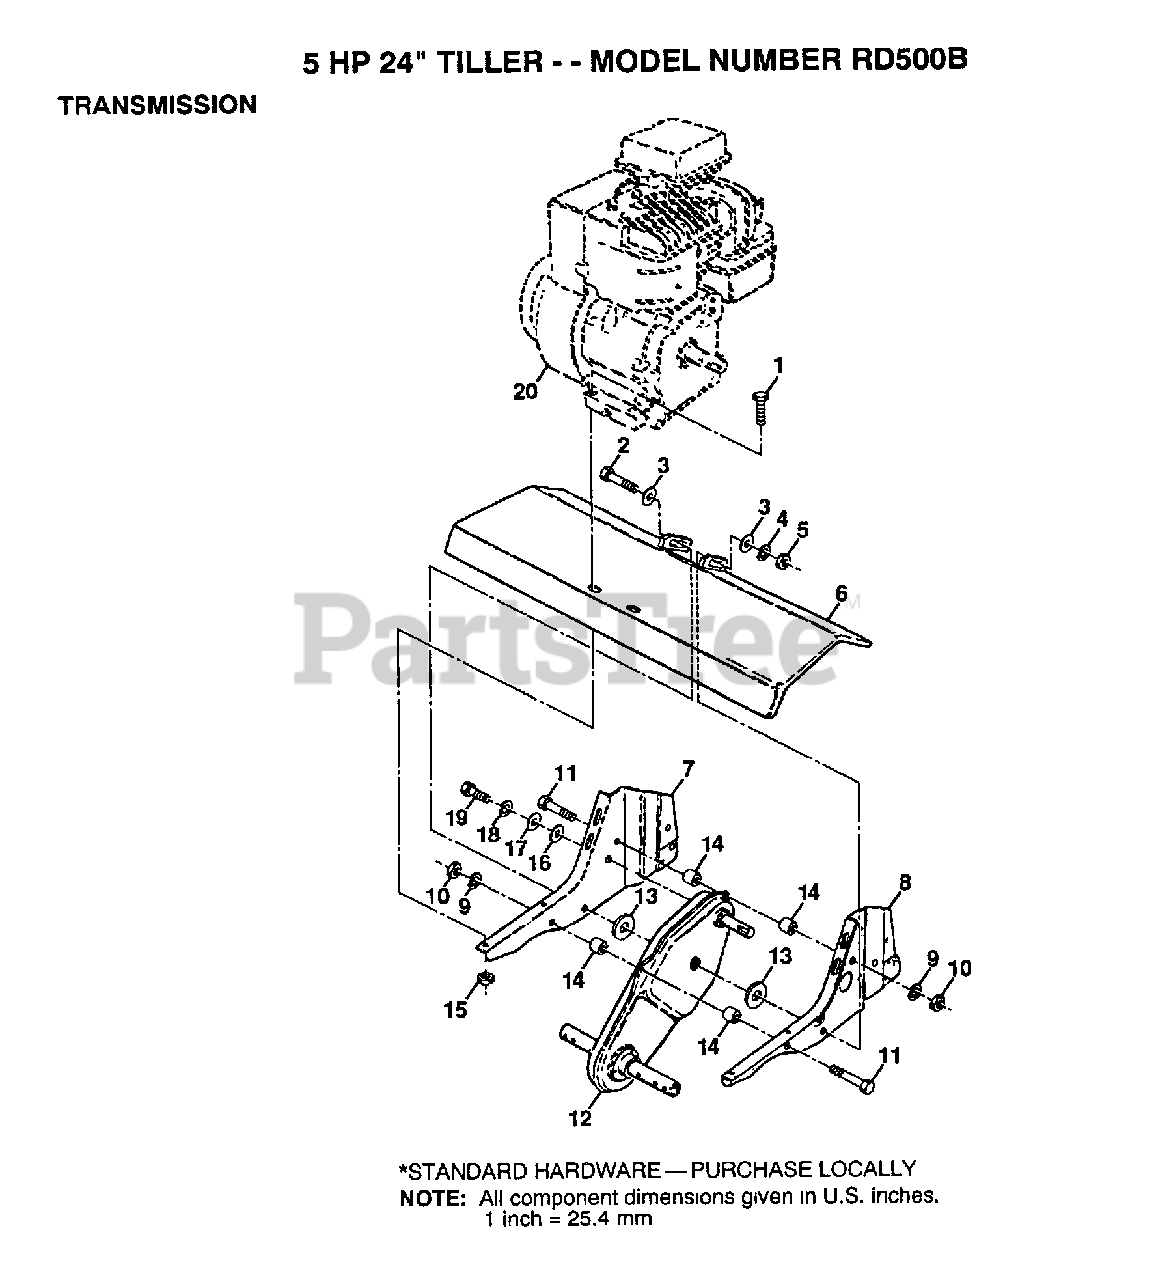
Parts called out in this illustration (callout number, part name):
1	BOLT.HEX.5/16-1.5
2	BOLT.3/8-24X3.75
3	WASHER
4	LOCKWASHER
5	GRIPCO NUT
8	BRACKET.ENG.LH.
9	LOCKWASHER
10	NUT.HEX.5/16-18
14	SPLIT SPACER RT
16	WASHER
17	WASHER
18	LOCKWASHER
19	BOLT
